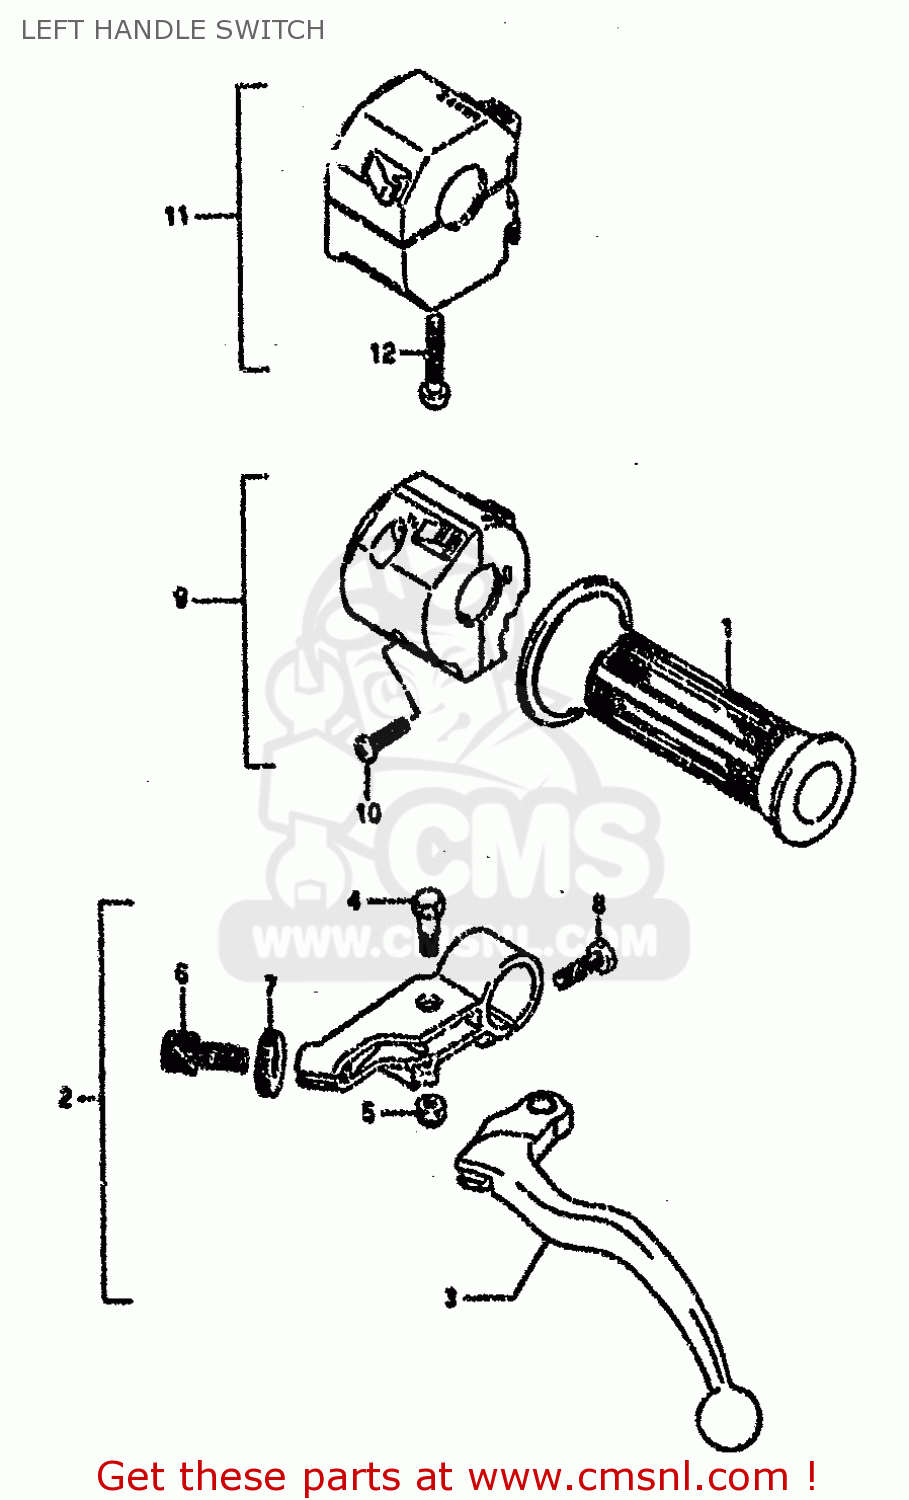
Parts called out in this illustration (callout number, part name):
1	GRIP,L
2	LEVER ASSY,CLUTCH
3	LEVER,CLUTCH
4	BOLT,LEVER
5	NUT
6	ADJUSTER,CABLE
7	NUT,CABLE ADJUSTER LOCK
8	BOLT
9	SWITCH ASSY,HANDLE,LH
10	SCREW 5X20
11	SWITCH ASSY,L
12	SCREW
